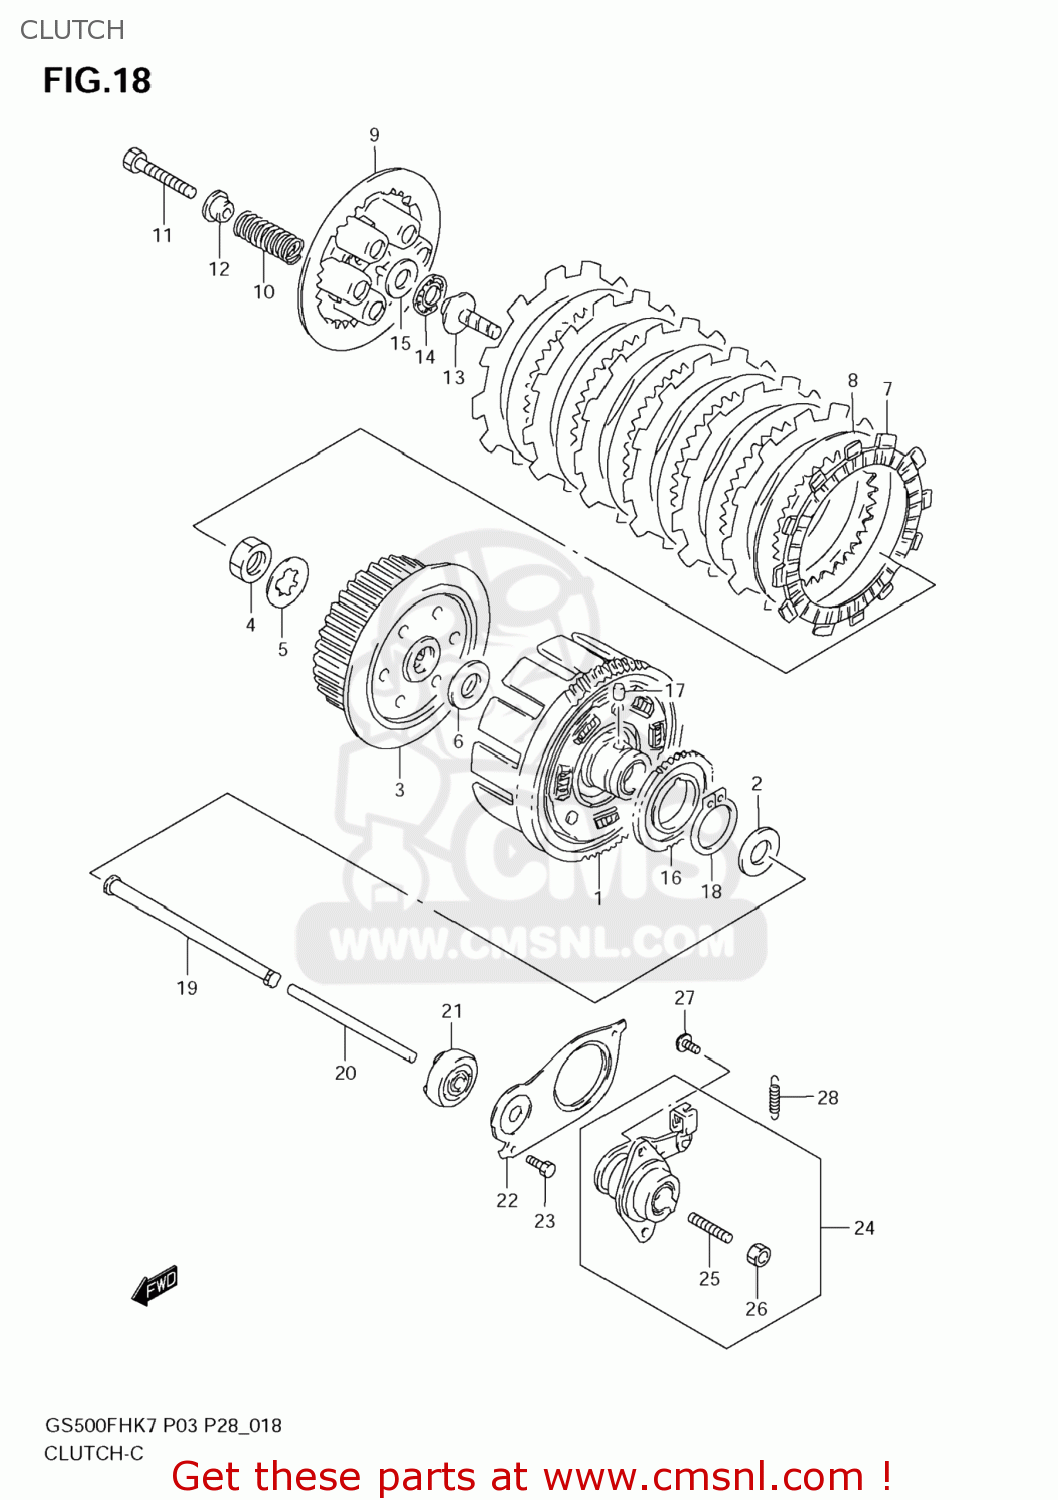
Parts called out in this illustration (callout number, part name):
1	GEAR ASSY,PRI DRIVEN
2	SHIM(25X38X1)
3	HUB,CLUTCH SLEEVE
4	NUT
5	WASHER,LOCK
6	WASHER(20X44X3)
7	PLATE,CLUTCH DRIVE (NAS)
8	PLATE,CLUTCH DRIVEN(T:1.6) (NAS)
9	DISC,CLUTCH PRESSURE
10	SPRING
11	BOLT(6X40)
12	SPACER,CLUTCH SLEEVE HUB
13	PIECE,CLUTCH PUSH
14	BEARING(15X28X2)
15	WASHER(15.5X28X1)
16	GEAR,OIL PUMP DRIVE(NT:39)
17	PIN(6X6)
18	CIRCLIP
19	ROD,PUSH,R
20	ROD,CLUTCH PUSH,L
21	SEAL,OIL(6X34X10)
22	RETAINER,PUSH ROD OIL SEAL
23	BOLT
24	SCREW ASSY,CLUTCH RELEASE
25	SCREW(6X25)
26	NUT
27	SCREW
28	SPRING
